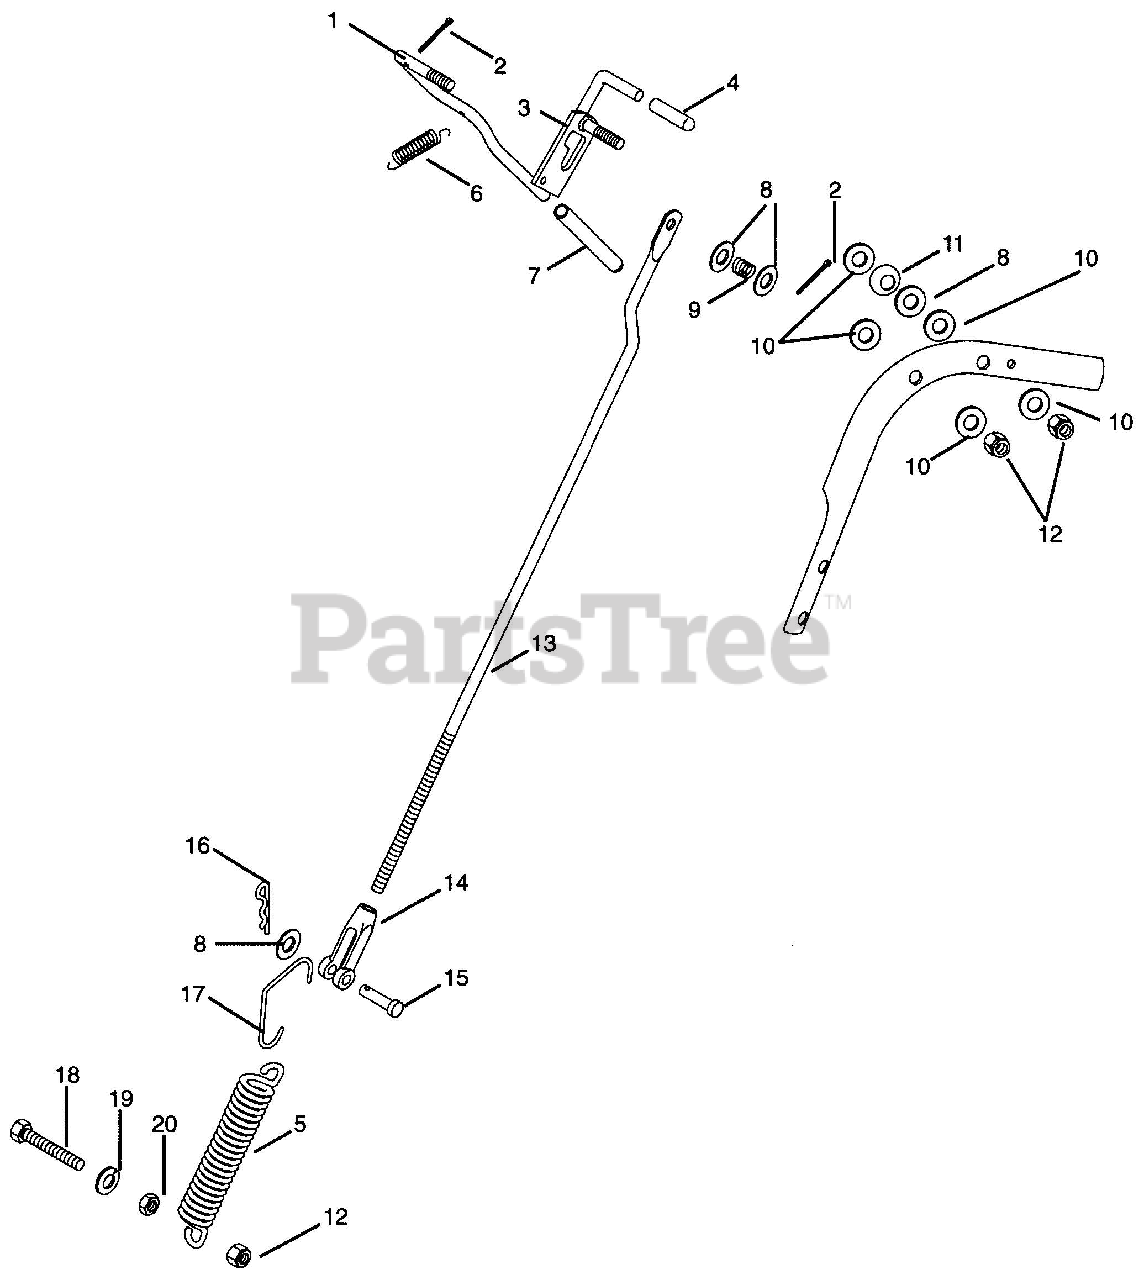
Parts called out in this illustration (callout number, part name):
1	Lever - Hand Control
2	Pin-Cotter .09 x .75
3	Weldment - Neutral Locking Lever
4	Tip-Brake Lock Lever
5	Spring - Tens .105 x 1.00 x 4.5
6	Spring - tens .041 x .500x 1.750
7	Grip-Hand Clutch Lever
8	Washer-Flat-Steel .406 x .812 x .065
9	Spring - Compression .045 x .600 x .750
10	Washer-Flat-Nylon .375 x .75 x .06
11	Washer-Spring .375
12	Nut-Locking-Center .38-16
13	Rod - Pump Control
14	Clevis .38-24 Adjustable
15	Pin-Clevis .370 x 1.50
16	Pin-Hair Internal .08 x .18 x 1.18
17	Hook - Spring
18	Bolt-Hex .38-16 x 2.50
19	Washer-Lock .375 x .094
20	Nut-Hex .375-16 Grade 5
